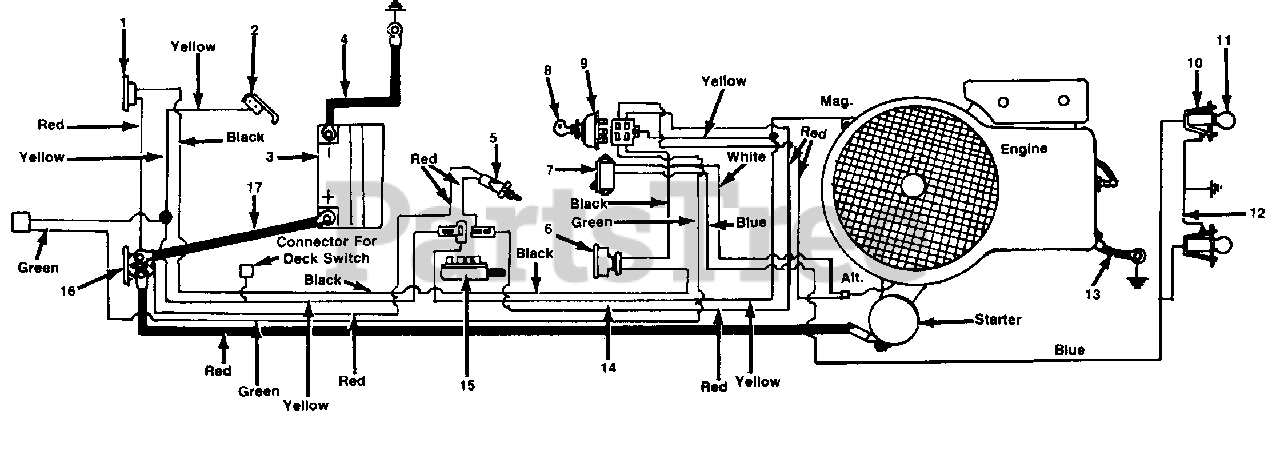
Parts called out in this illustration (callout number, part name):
1	Circuit Breaker
2	Spring Switch
3	12V Battery
4	Ground Wire 9.0" Lg.
5	Safety Switch
6	Ammeter
7	Light Switch
8	Ignition Key
9	Ignition Switch
10	Socket
11	Lamp
12	Grounding Wire
13	Ground Wire 7.25" Lg.
14	Wire Harness
15	Safety Switch
16	Solenoid
17	Electric Wire
